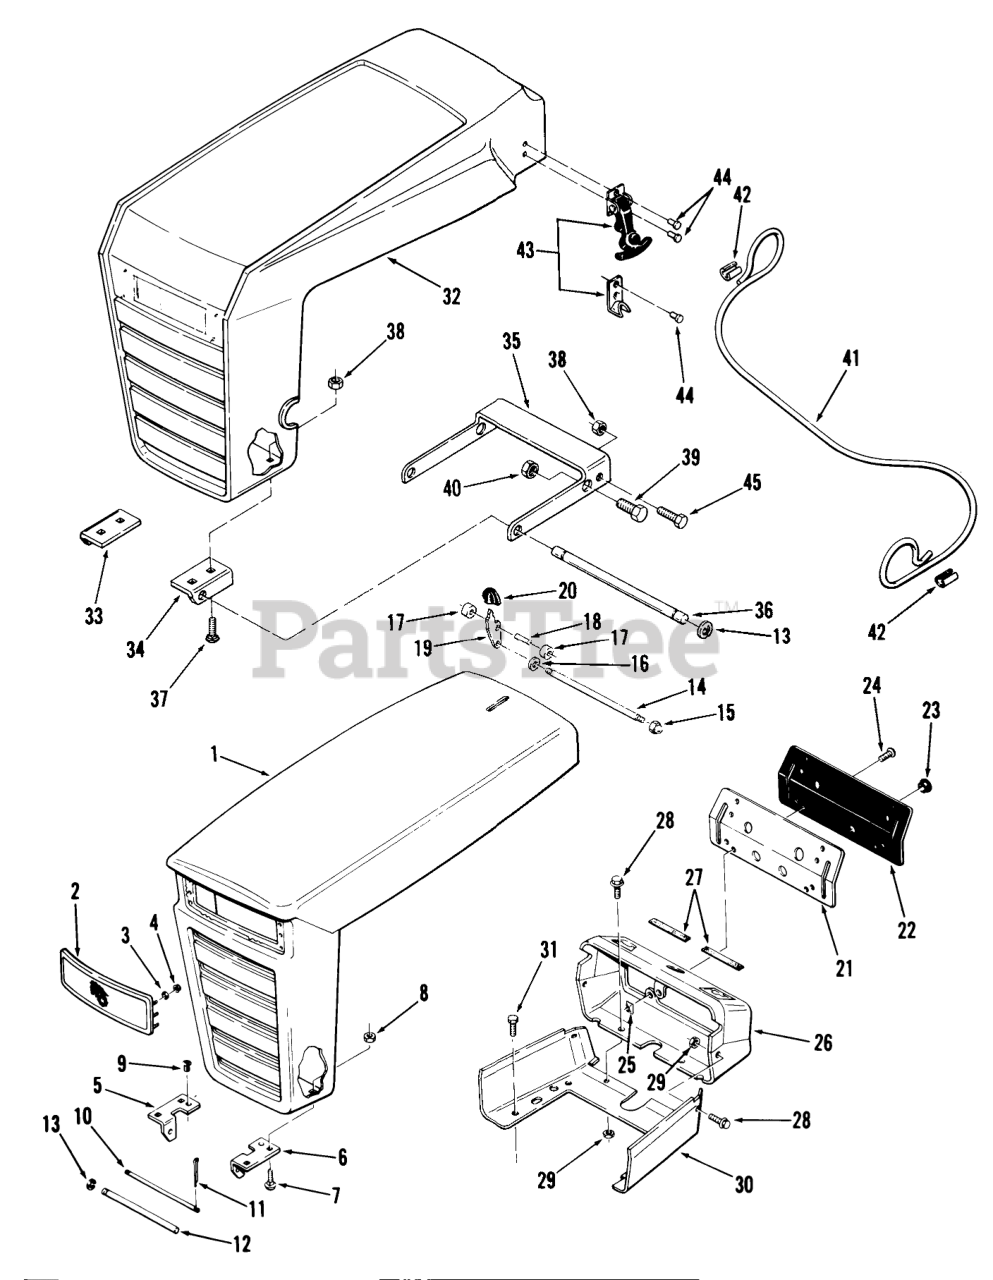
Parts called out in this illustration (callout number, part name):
2	ESCUTCHEON PLATE
4	SPEED NUT
9	GROMMET
10	ROD-HOOD STOP
12	GRILL PIVOT ROD
13	RING-RETAINING
18	SPIROL PIN
19	LEVER HOOD LATCH
20	KNOB
31	SCREW
43	ASSY-FLEX DRAW LATCH
44	RIVET
